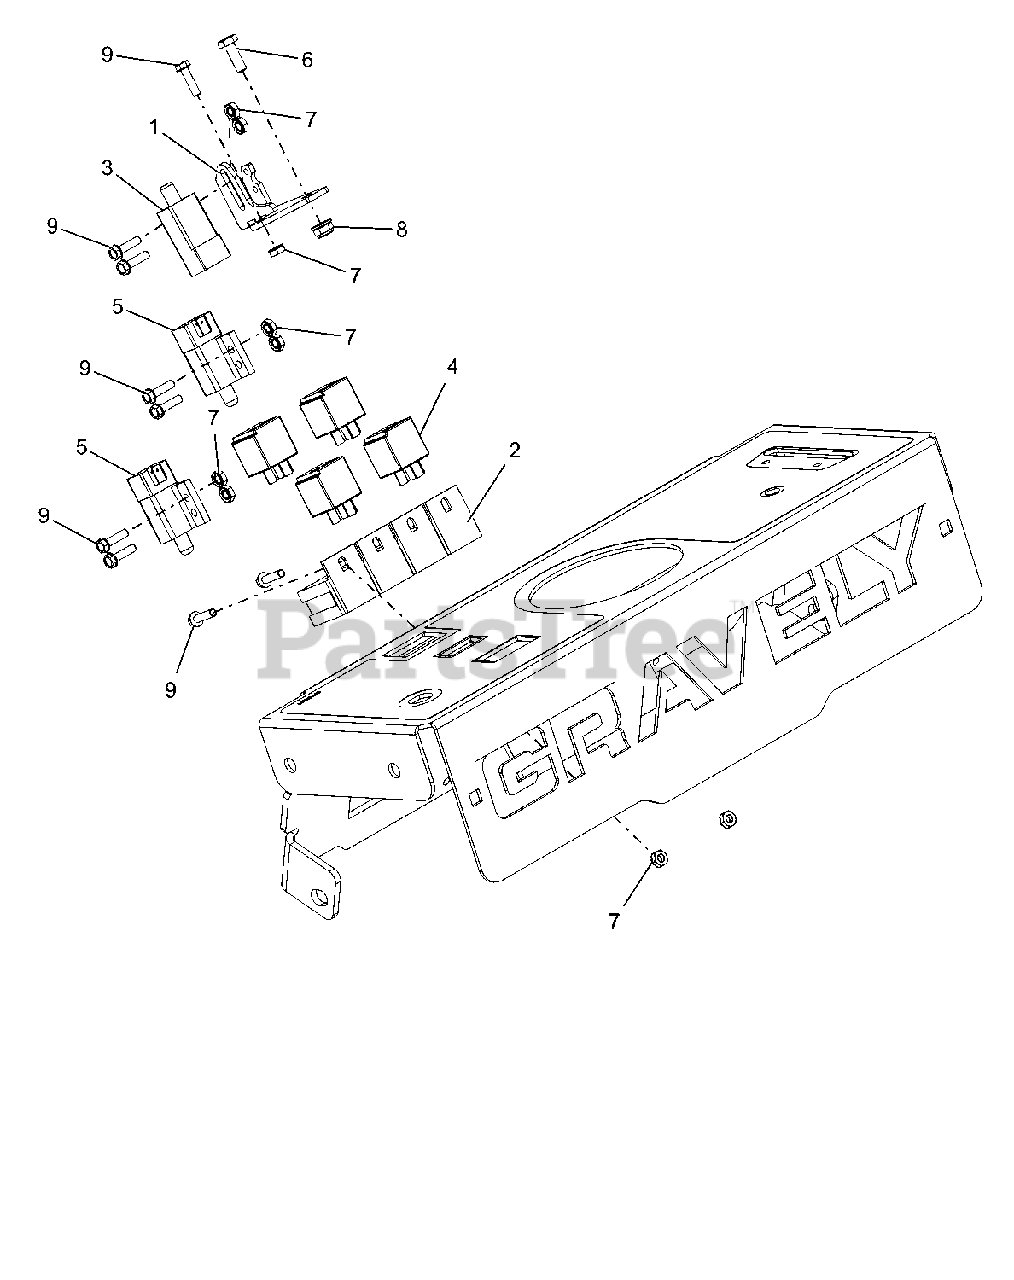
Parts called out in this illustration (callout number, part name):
1	WLDMT, SWITCH & SPRING-BLACK
2	HARNESS, WIRE MY14 JDCWBM
3	SWITCH, INTERLOCK REV C
4	RELAY, ISO MINI ELEC.
5	SWITCH, PLUNGER DP-N.O.-N.C.
6	BLT-HEX .25-20X.75 GR5 YWZC
7	NUT-KEPS 10-24
8	NUT-LK-NYL-FLG .25-20 YWZC
9	@SCR-MCH 10-24X.75 HWH YWZC
